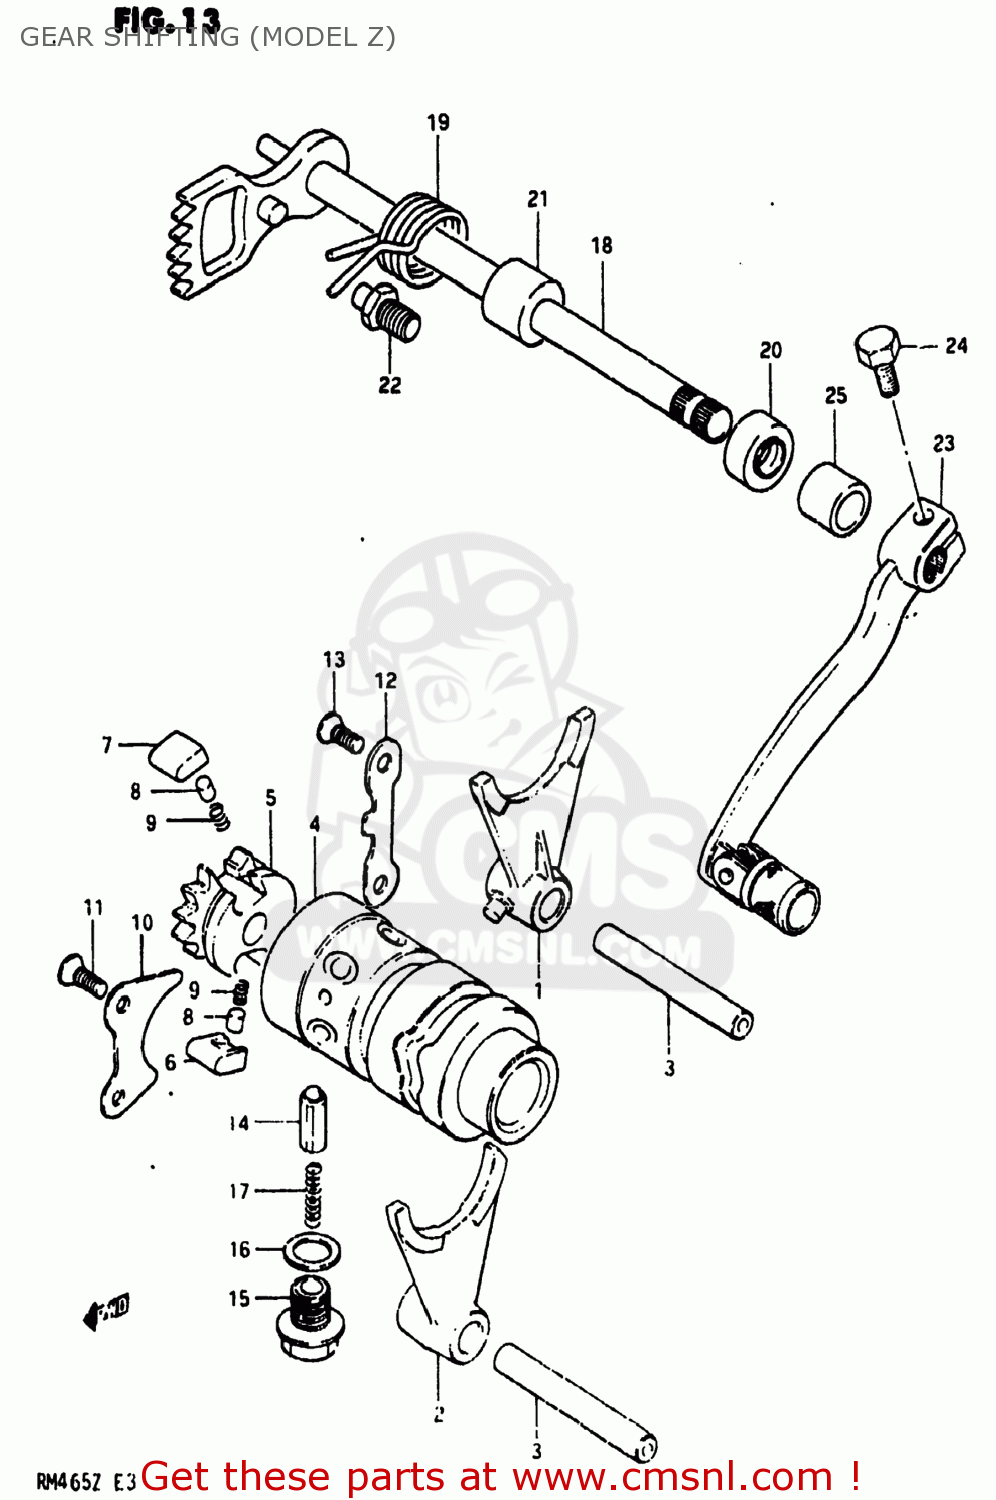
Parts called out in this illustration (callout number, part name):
1	FORK,GEAR SHIFT NO.1
2	FORK,GEAR SHIFT NO.2
3	SHAFT,GEAR SHIFT FORK
4	CAM,GEAR SHIFT
5	RETAINER,GEAR SHIFT CAM
6	PAWL,GEAR SHIFT NO.1
7	PAWL,GEAR SHIFT NO.2
8	PIN(5X8)
9	SPRING
10	LIFTER,GEAR SHIFT PAWL
11	SCREW
12	GUIDE,GEAR SHIFT CAM
13	SCREW
14	STOPPER,GEAR SHIFTING
15	BOLT,GEAR SHAFT CAM STOPPER
16	GASKET(14X19.2X2) (NAS)
17	SPRING
18	SHAFT,GEAR SHIFT
19	SPRING
20	OIL SEAL
21	SPACER(12X20X15.3)
22	STOPPER,GEAR SHIFT CAM
23	LEVER ASSEMBLY,GEAR SHIFTING
24	BOLT
25	SPACER(12X20X15.3)
